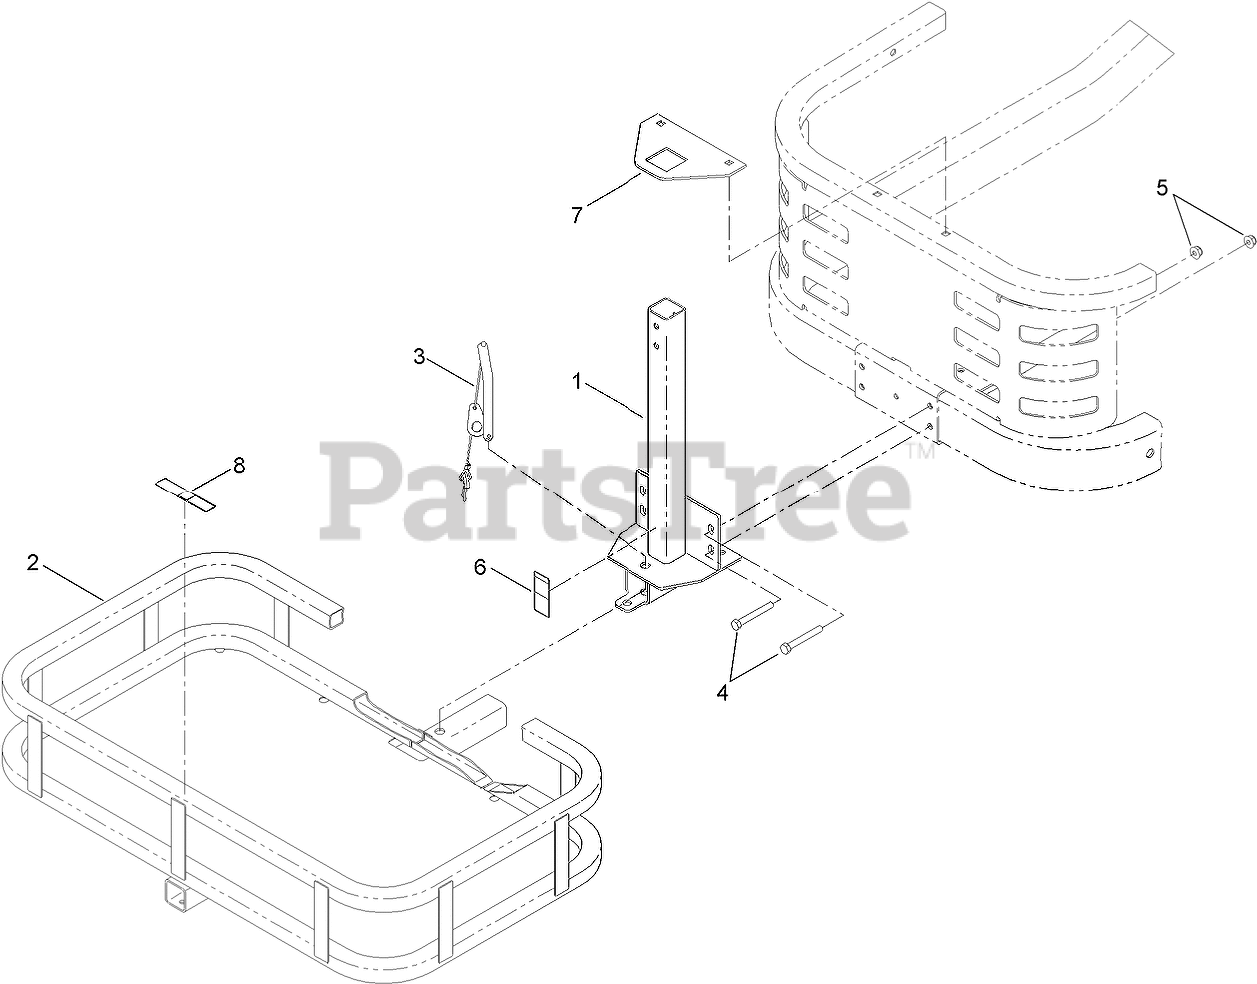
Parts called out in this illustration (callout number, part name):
1	MOUNT-TRAY
2	TRAY-CARRIER
3	PIN-ROPS
4	SCREW-HH
5	NUT-HF, NI
7	PLATE-SUPPORT
8	DECAL-MAXIMUM WEIGHT
